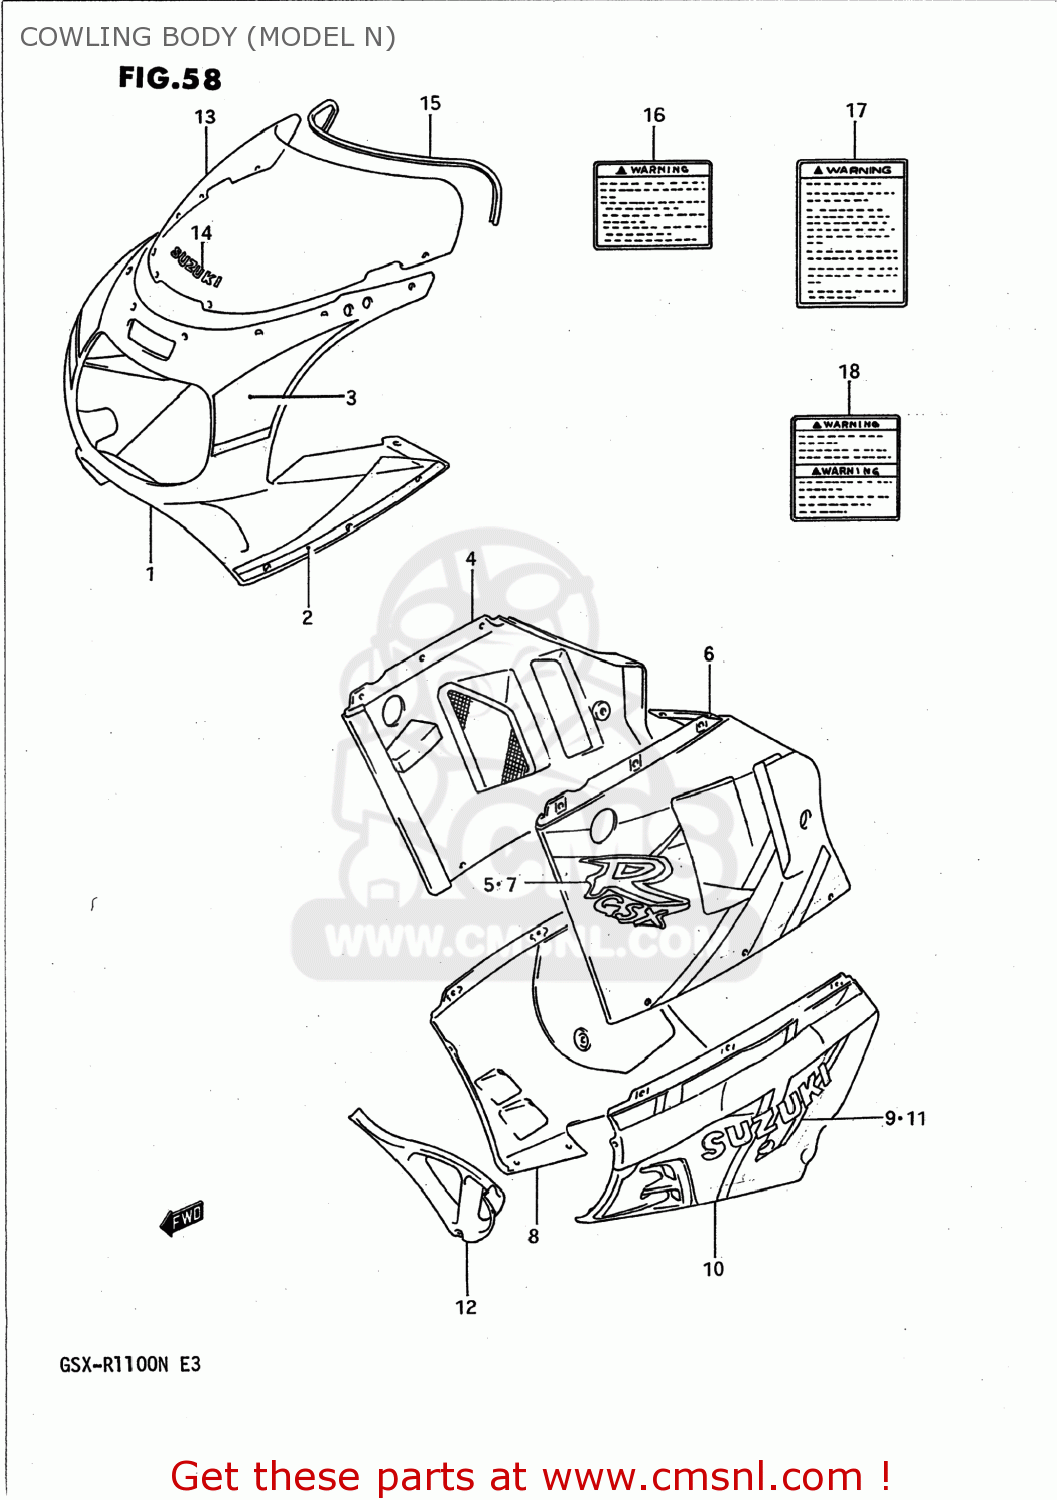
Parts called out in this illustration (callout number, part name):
1	BODY ASSY,COWLING
2	TAPE SET,COWLING,UPPER SIDE
3	TAPE SET,COWL UPR FR
4	COVER,COWLING SIDE,R
5	TAPE SET,COWLING SIDE
6	COVER COMP,COWLING SIDE,LEFT
7	TAPE SET,COWL SIDE,L
8	COWLING,UNDER,R(WHITE)
9	TAPE,COWL UNDER STRIPE,R
10	COWLING,UNDER,L(WHITE)
11	TAPE,COWL UNDER STRIPE,L
12	COWLING,UNDER,CENTER (W
13	SCREEN SET,WIND
14	EMBLEM,WINDSCREEN
15	MOLDING,WINDSCREEN
16	LABEL
17	LABEL (WARNING SCREEN)
18	LABEL (WARNING)
